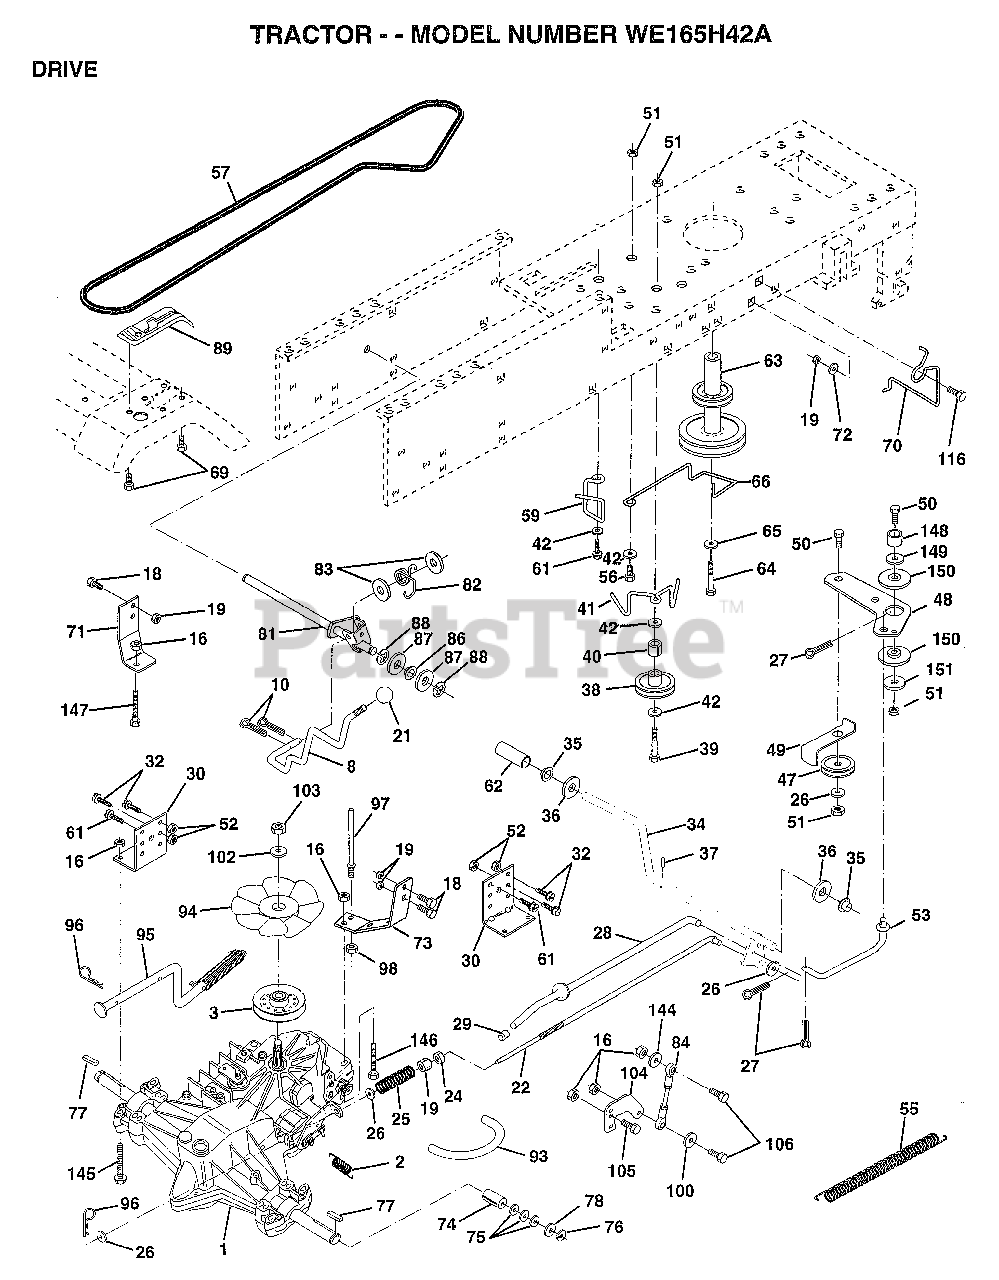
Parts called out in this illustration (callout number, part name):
1	TRANSAXLE.3100650
2	SPRING RET BRAKE
3	PULLEY.TRANSAXLE
8	ROD SHIFT FEND LT
10	PIN COTTER 1/8
16	NUT
18	BOLT
19	NUT
21	KNOB T (1/2-HOLE)
22	ROD.BRAKE.HYDRO.
24	NUT
25	SPRING ROD LT
26	WASHER
27	COTTER PIN
28	ROD.BRAKE.PARK.LT
29	PLUNGER CAP T
30	TRANSAXLE MTG BKT
32	BOLT
34	SHAFT ASM-PEDAL F
35	NYLON BEARING
36	WASHER LT
38	PULLEY.IDLER.FLAT
39	BOLT
40	SPACER T
42	WASHER
48	BELLCRANK.CLUTCH
49	RETAIN BELT
53	"LINK, CLUTCH T"
55	"SPRING, RETURN LT"
57	V-BELT.GROUND.HYD
59	KEEPER BELT CNTSP
61	SCREW
62	PEDAL COVER T
63	PULLEY.ENGINE
64	BOLT
65	LOCKWASHER
66	ENGINE BELT KEEPR
69	SCREW HEXWSH H-L
70	KEEPER BELT ENG
71	STRAP TORQ LH HYD
72	WASHER
73	"STRAP-TORQUE,RH"
74	SPACER SPLIT
76	E-RING LT
77	SQUARE KEY
78	WASHER
81	SHAFT.ASM.CROSS
82	"SPRING,TORSION"
83	WASHER
84	ROD.TIE
86	BUSHING
87	WASHER D
88	KLIP RING
93	"LINE FUEL HYD 4"""
94	"FAN 7"" HYDRO"
97	BOLT KEEPER RH
98	NUT
100	WASHER M
102	WASHER BELLEVILLE
104	ARM CONTROL HYDRO
105	SCREW CAP 5/16-18
106	BOLT
116	BOLT RDHD 3/8-16
144	WASHER
145	BOLT.HEX.FLGHD
146	BOLT.HEX.FLGHD.
147	BOLT.HEX.FLGHD
149	SPACER RETAINER
150	BUSHING.NYLON
151	WASHER
